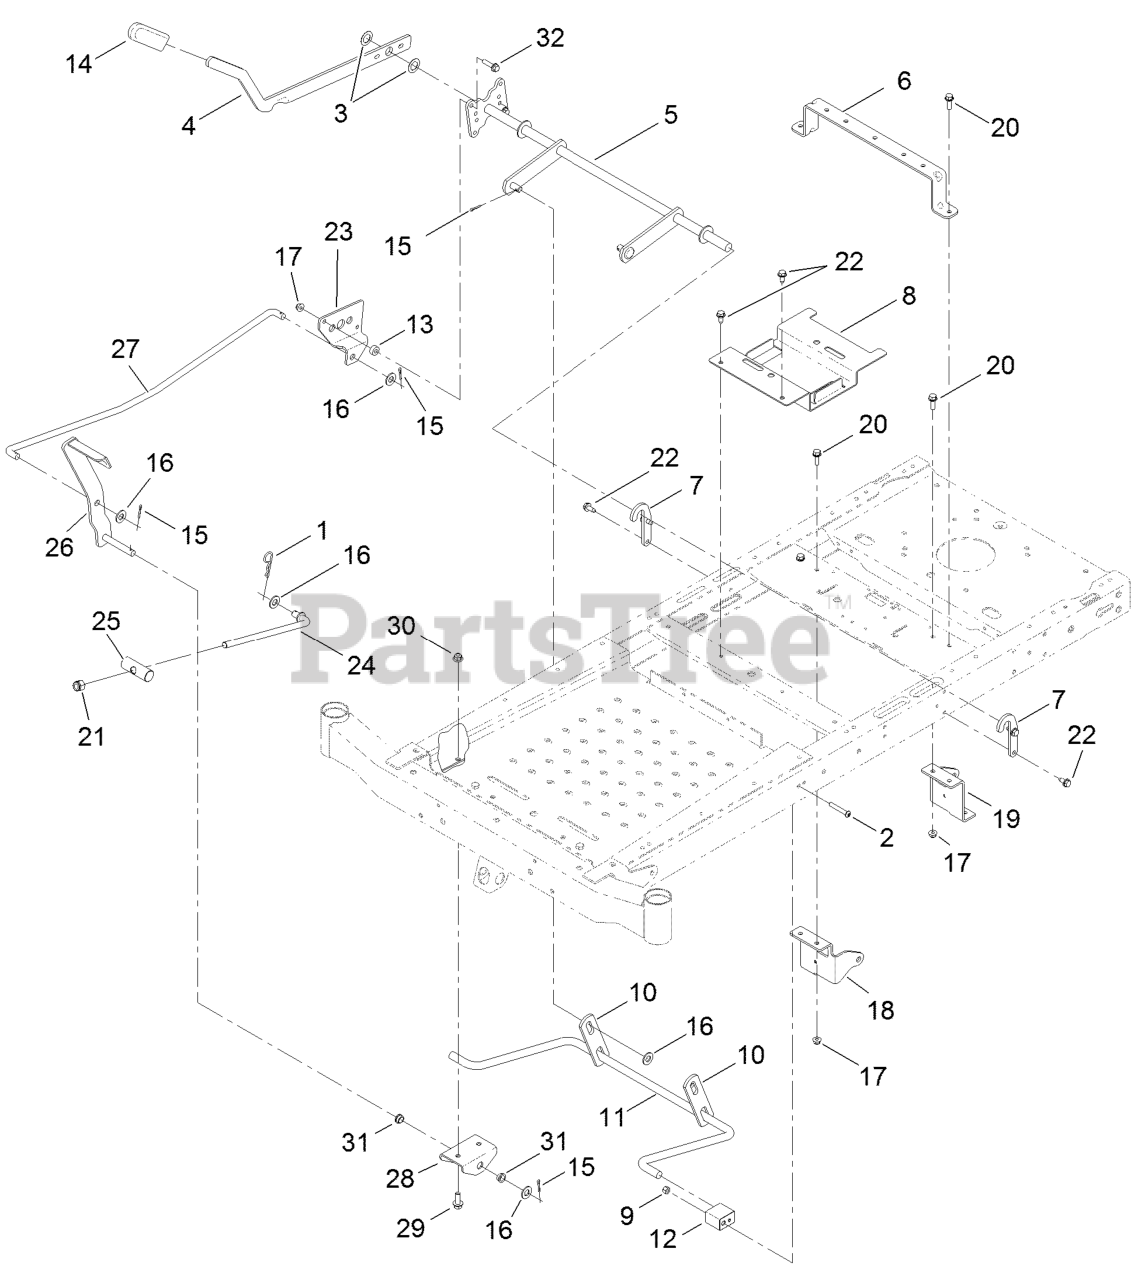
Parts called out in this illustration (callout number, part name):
1	PIN-COTTER
2	SCREW-HSBH
3	WASHER-THRUST
4	LEVER-LIFT
6	BRACE-SEAT, REAR
7	BRACKET-LIFT
8	BRACKET-BATTERY
9	NUT-LOCK, NI
10	LINK-LIFT
11	ARM-LIFT, REAR (WIDE)
12	BLOCK-PIVOT
14	GRIP-LEVER
15	PIN-COTTER
16	WASHER-FLAT
17	NUT-HF, NI
18	MOUNT-HYDRO, FRONT (RH)
19	MOUNT-HYDRO, FRONT (LH)
20	SCREW-HHF
21	NUT-HEX
22	Screw-HWH 5/16-18 X 3/4 Tf
23	PLATE-FOOTLIFT
25	PIN-PIVOT
26	PEDAL ASM
27	ROD-FOOTLIFT
28	BRACKET-FOOTLIFT
29	SCREW-HHF 3/8-16 X 1
30	NUT-HF, NI
31	BUSHING-FLANGE
32	SCREW-HHF
